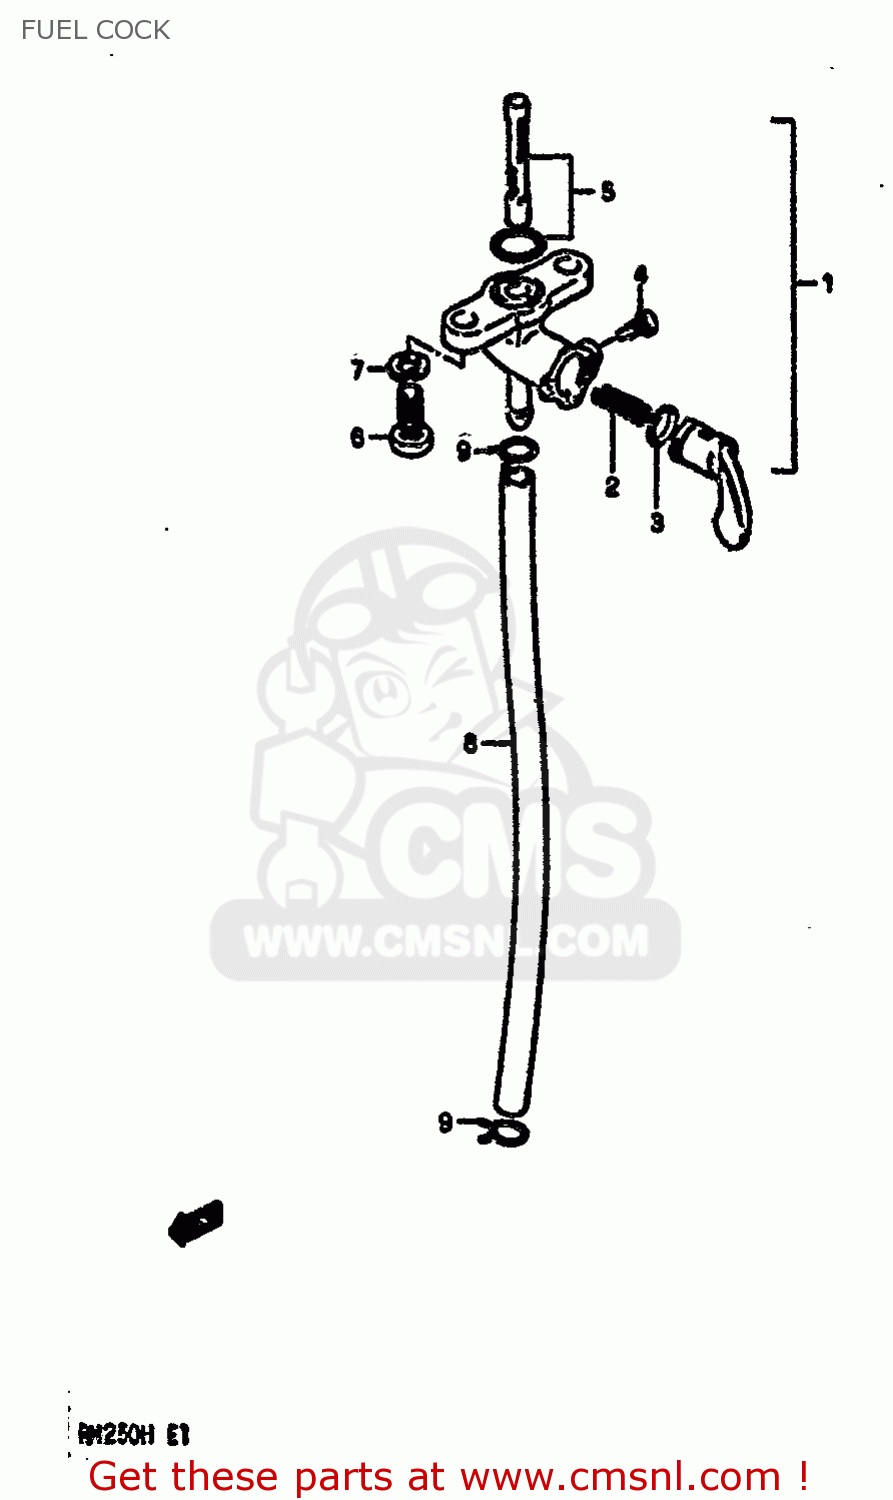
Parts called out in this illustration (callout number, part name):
1	COCK ASSY,FUEL
2	SPRING,FUEL COCK VALUE
3	O RING,LEVER
4	SCREW
5	FILTER SET FUEL
6	SCREW
7	WASHER,LOCK
8	HOSE
9	CLIP
